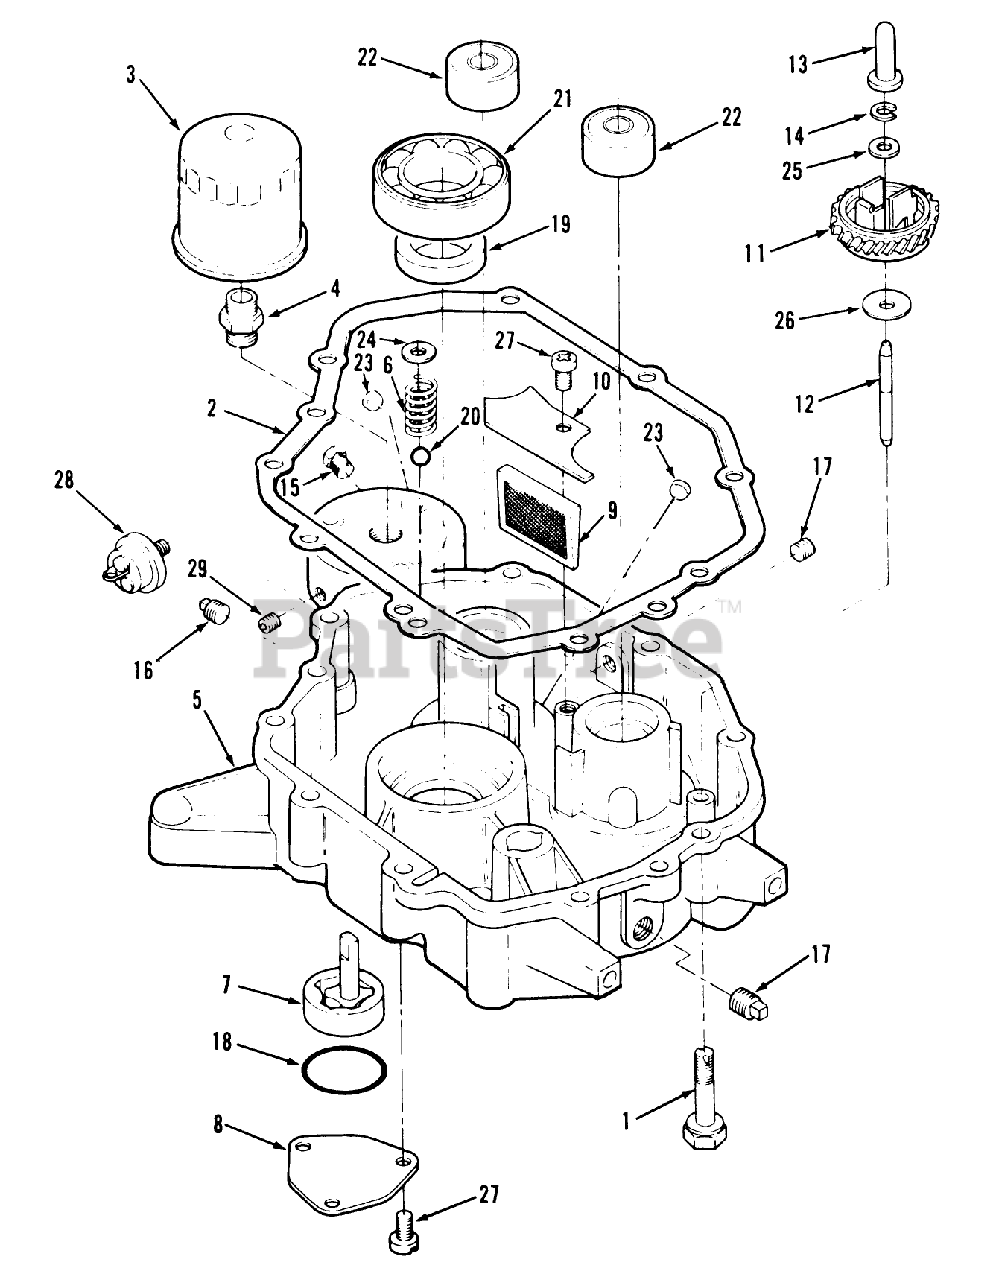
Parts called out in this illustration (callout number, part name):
1	SELF-TAP BOLT SP M8
4	Oil Filter Adapter
19	SEAL-OIL CRNKSHFT UP
28	SWITCH-OIL PRESSURE
